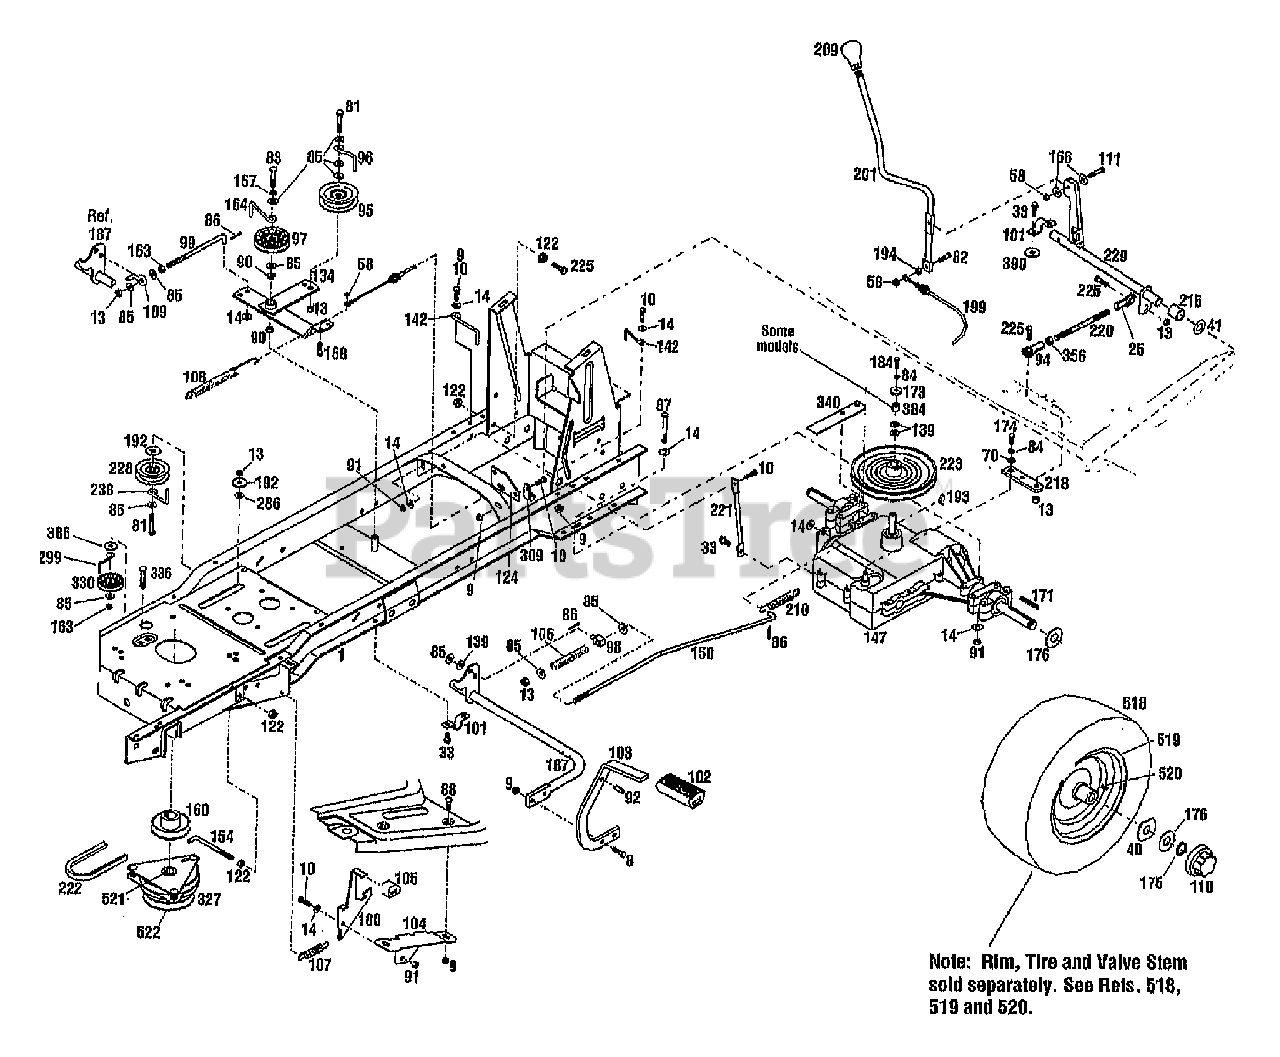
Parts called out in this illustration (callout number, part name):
1	ASSM-FRAME LTX
8	SCR-HH 5/16-18X1.0 G5 ZP
9	NUT-HFLK 5/16-18 ZP
10	SCR-HHC 5/16-18X.75 GR 5 ZP
13	NUT-LOCK 3/8-16
14	WASHER-FLAT 5/16 SAE
25	JOINT-BALL
33	SCR-HFLK 5/16-18X.75
40	WASHER-SPEC .75X2.50
41	WASHER-THRUST
58	NUT-HT LK 1/4-20
70	WASHER-FLAT 1/4 SAE
81	SCR-HH 3/8-16X2.0 G5 ZP
82	SCR-HH 1/4-20X1.0
83	SCR-HH 3/8-16X1.75 G5 ZP
84	WASHER-LK .25 ZP
85	WASHER-FLAT 3/8 SAE
86	PIN-COTTER .09X.75 ZP
87	SCR-HH 5/16-18X2.75 G5 ZP
88	SCR-CARR 5/16-18X.62 G2 ZP
90	BUSHING-.5X.5 NYLON FLNG
91	NUT-TOP/LK 5/16-18 ZP
92	PIN-.312X.75
94	JOINT-BALL
96	GUIDE-BELT
97	PULLEY-IDLER
99	ROD-CLUTCH
100	LATCH-BRAKE CLUTCH USE1771514
101	CLIP-CLAMP .75 ID
102	PAD-FOOT PEDAL
103	PEDAL-BRAKE
104	BRKT-BRAKE LOCK
105	PAD-BRAKE
106	SPRING-COMPRESSION
107	SPRING-EXTENSION
108	SPRING-EXTENSION
109	ROD-PIVOT
110	CAP-HUB
111	SCR-HFLK 1/4-20X1.00
122	NUT-HFLK 3/8-16 ZP
124	SUPPORT-CABLE
134	PLATE-IDLER
139	WASHER-FLAT .375DIA
142	GUIDE-BELT
147	TRANSAXLE, PEERLESS 930
150	ROD-BRAKE
154	RETAINER-CLUTCH
160	PULLEY-ENGINE
163	NUT-HEX 3/8-16 ZP
164	GUIDE-BELT
166	WASHER-FLAT 1.25X.28X.062 ZP
167	WASHER-LK .375 @ DEPL
168	SCR-HH 1/4-20X.75 G5 ZP
171	KEY-.188 SQ X 2.0
173	WASHER-.865X.281X.1793
174	SCR-HHC 1.4-28 X .50
175	RING-RET."E".577 ID
176	WASHER-1.87X.765X.06 SPECIAL
184	SCR-HH 1/4-20 X .875
187	ASSM-BRAKE PEDAL
192	WASHER-1.12X.378X.125
193	KEY-WOODRUFF .188X.75
194	NUT-HEX 1/4-20 ZP
199	CABLE-SHIFT
201	ARM-SHIFT
210	SPRING-EXTENSION
215	SPACER
218	ARM-TRANSMISSION
220	ROD-ADJUSTING
221	SUPPORT-TRANS
223	PULLEY-TRANSMISSION
225	SCR-HH 3/8-16X1.25
228	IDLER-SHEAVE 3" X 1"
229	SHAFT-PIVOT
238	GUIDE-BELT
286	WASHER-.75X.406X.092
299	GUIDE-BELT
309	CLIP-J
327	CLUTCH-ELECTRIC
330	PULLEY-IDLER
340	STOP-TRANSMISSION
356	NUT-HEX/JAM 3/8-24 ZP
384	SPACER-625X.376X.625
386	WASHER-1.06X.531X.1 ZP
390	WASHER-.632X.39X.0329
518	TIRE-20X8.00-10
519	DISC-WHEEL
520	STEM-VALVE
